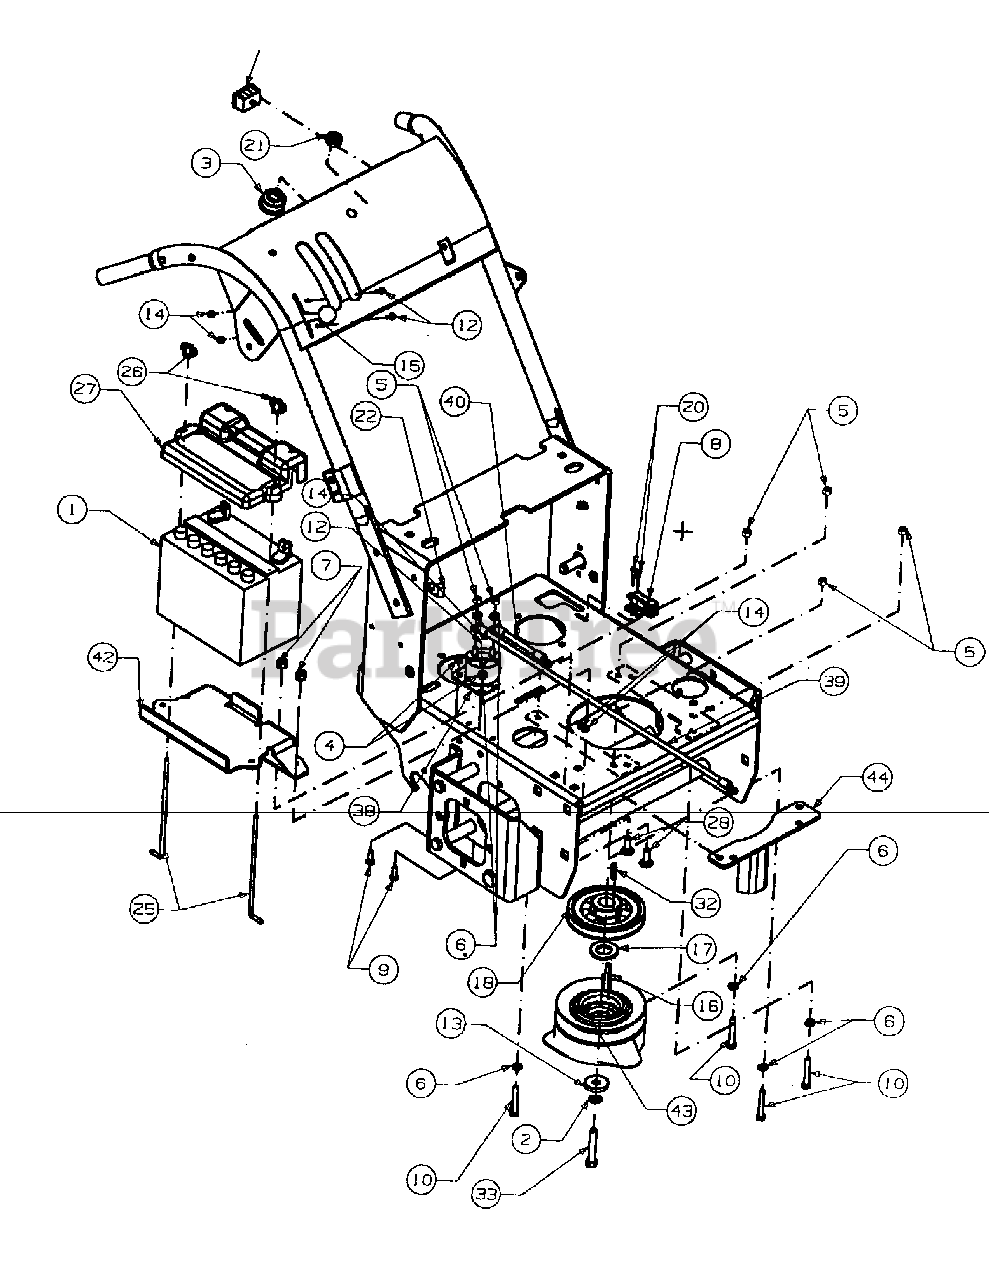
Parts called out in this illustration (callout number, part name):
1	BTTRY : 12V 225CCA
2	WASH:LCK:M10: METRIC:ZINC
3	SW:IGN:GRNSMWR:ZTR/HYD-WB
4	NUT:L:NYL INS:1/4-20 GR A
5	NUT:5/16-18:NYLOCK
6	WASH:LCK:5/16:ZINC
7	NUT:L:NYL INS:3/8-16 GR A
8	SW:DELTA NO/NC
9	HHCS:1/4-20:.75:GR5:STD
10	HHCS:STD:5/16-18 X 2:GR5
11	BOOT:1"OD RBR:BTTRY-PST RED
12	SCR:HX WASH w/SLOT:10-32X1/2
13	WASH:CLU:PLTD
14	NUT:L:NYLON INS:#10-32 GR A
15	CONT:THROT:W/DETENT 39.2
16	KEY STCK:1/4X1/4X2
17	WASHER SPECIAL
18	SHEAV:1" BORE W/2 SET SCRS
19	BELT : HYDRO PUMP
20	SCR:PH HD:MACH:10-32 X 5/8
21	NUT:W/CAP:5/8-32 IGNITION
22	CLAMP:SUPT:3/8 OD
23	CBL:BATTRY:10 1/4":BLACK
24	BRKT:MFLR:KAWASAKI
25	ROD:HLDDN:BAT
26	NUT:WING:1/4-20.W/ BELL WASH
27	CVR:BATT LARGE
28	BOLT:CARR 3/8-16 X 2 GR 5
29	CLAMP ASSY:MUFFLER
30	ENG: 7HP:KAWASAKI
32	KEYSTCK:1/4 X 1/4 X 1
33	CAPSCREW:M10-1.5 X 60mm ZN
34	MTR:HOUR
35	HARN:HOUMETER
36	MANIFOLD:KAWA
37	HARN:KAWA:WIDE TRACK
38	SOLENOID:MAGNETIC SWITCH
39	CBL:BATTRY:RED:24"
40	CBL:BATTRY:RED:5"
41	HARN :KAWA: ADAP
42	BRKT : BTRY :WELDED
43	PTO CLUTCH
44	BRKT ASM: CLU: RET
